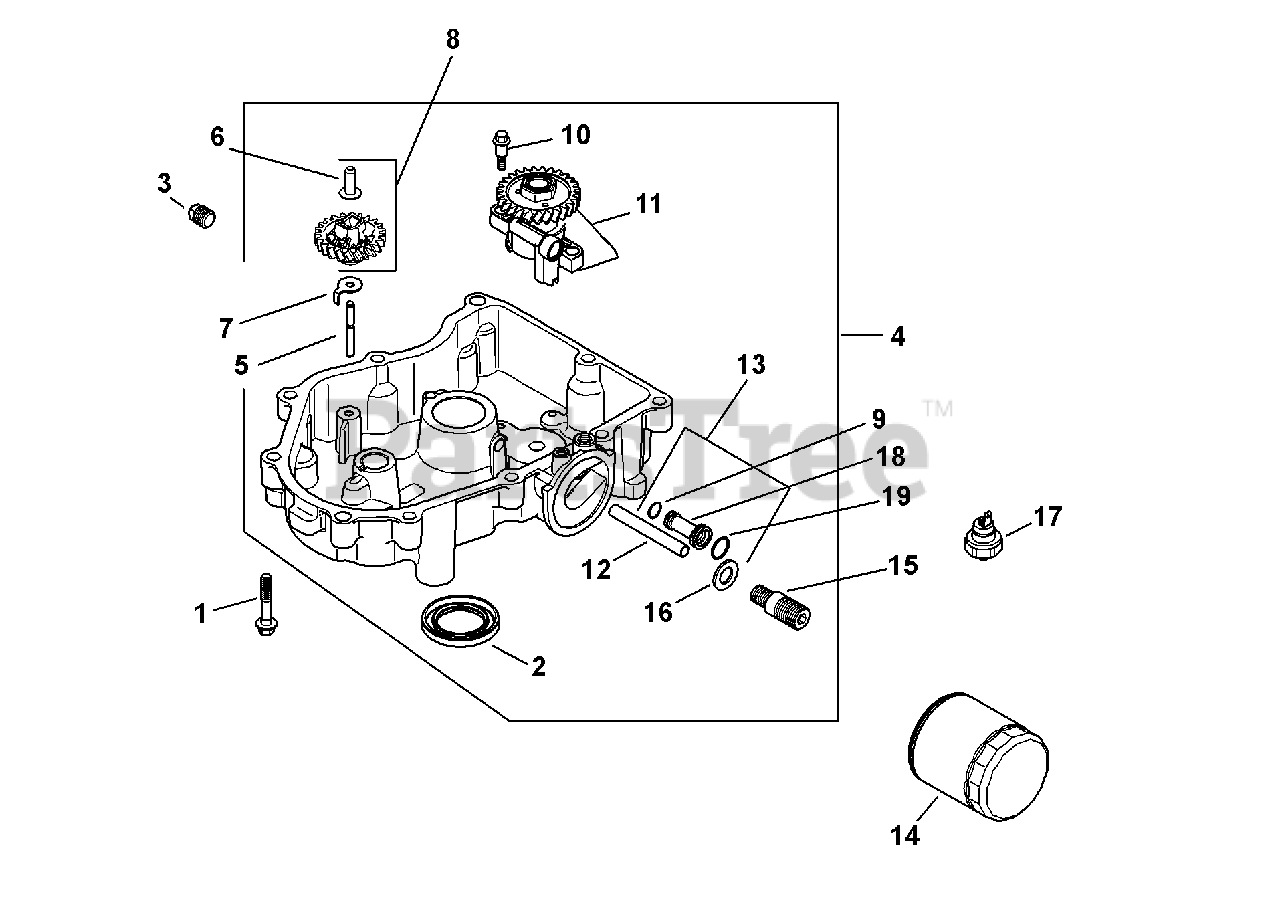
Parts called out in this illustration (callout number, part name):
1	Flange Screw, M8 x 1.25 x 45
2	Oil Seal, 2.38 x 1.45
3	Square Head Pipe Plug, 3/8
4	Oil Pan Assembly
5	Governor Gear Shaft
6	Governor Regulating Pin
8	Governor Gear Kit
9	Oil Pick-Up O-Ring
11	Oil Pump Assembly
12	Oil Feed Tube (Filter to Oil Pan)
13	Oil Feed Tube Assembly
15	Oil Filter Nipple
17	Oil Pressure Switch
18	Oil Feed Tube
